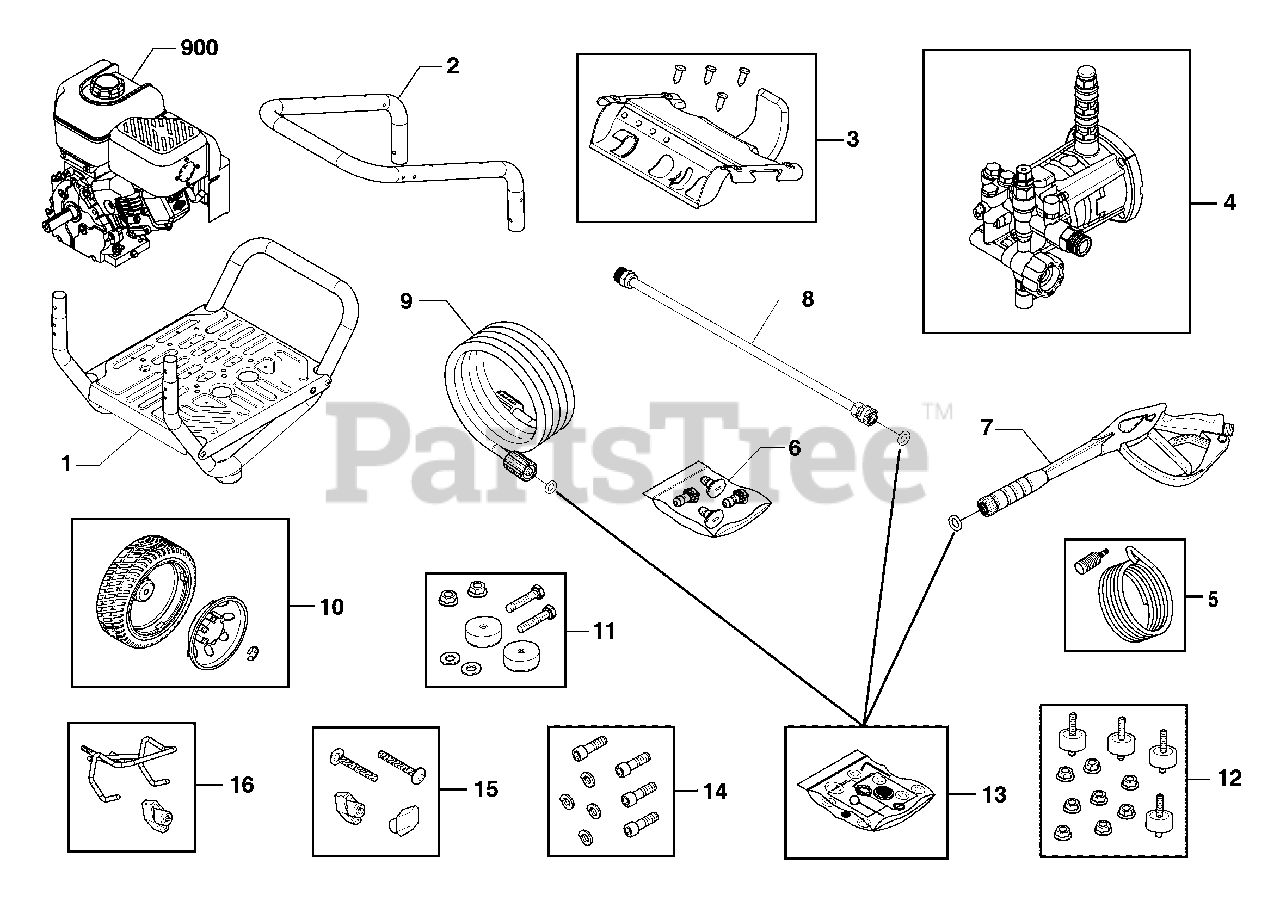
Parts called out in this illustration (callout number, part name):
5	KIT, Chem Hose & Filter
6	KIT-QC NOZZLES
8	EXTENSION, QC
11	KIT, Vibration Mount
12	KIT, Vibration Mount
13	KIT-O-RING MAINTENANCE
14	KIT, Hardware, Pump Mounting
15	KIT, Hardware, Handle
16	KIT, Gun Holder, Weldment
